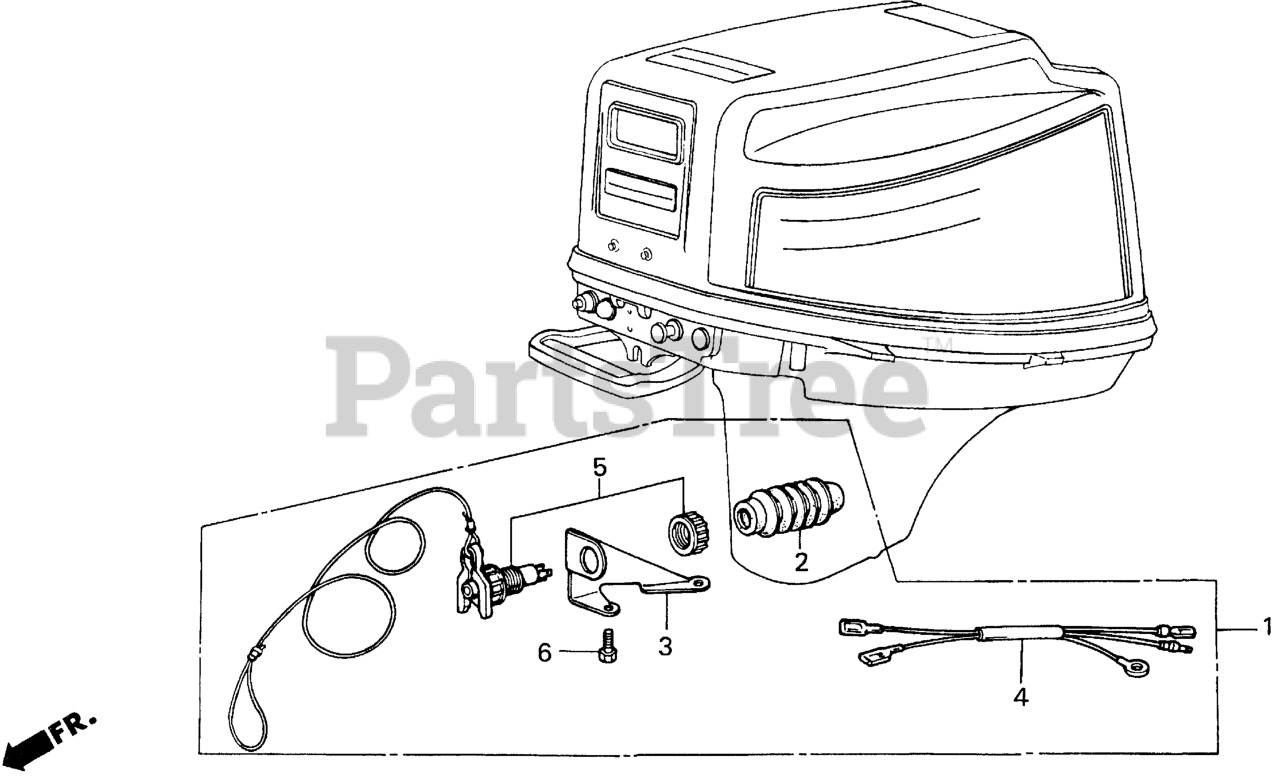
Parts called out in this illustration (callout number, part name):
1	SWITCH KIT, SAFETY
2	RUBBER, SEALING (NOT AVAILABLE)
3	STAY, SAFETY SWITCH (NOT AVAILABLE)
4	WIRE B, SWITCH
5	SWITCH, SAFETY
6	BOLT, HEX. (6X12)
